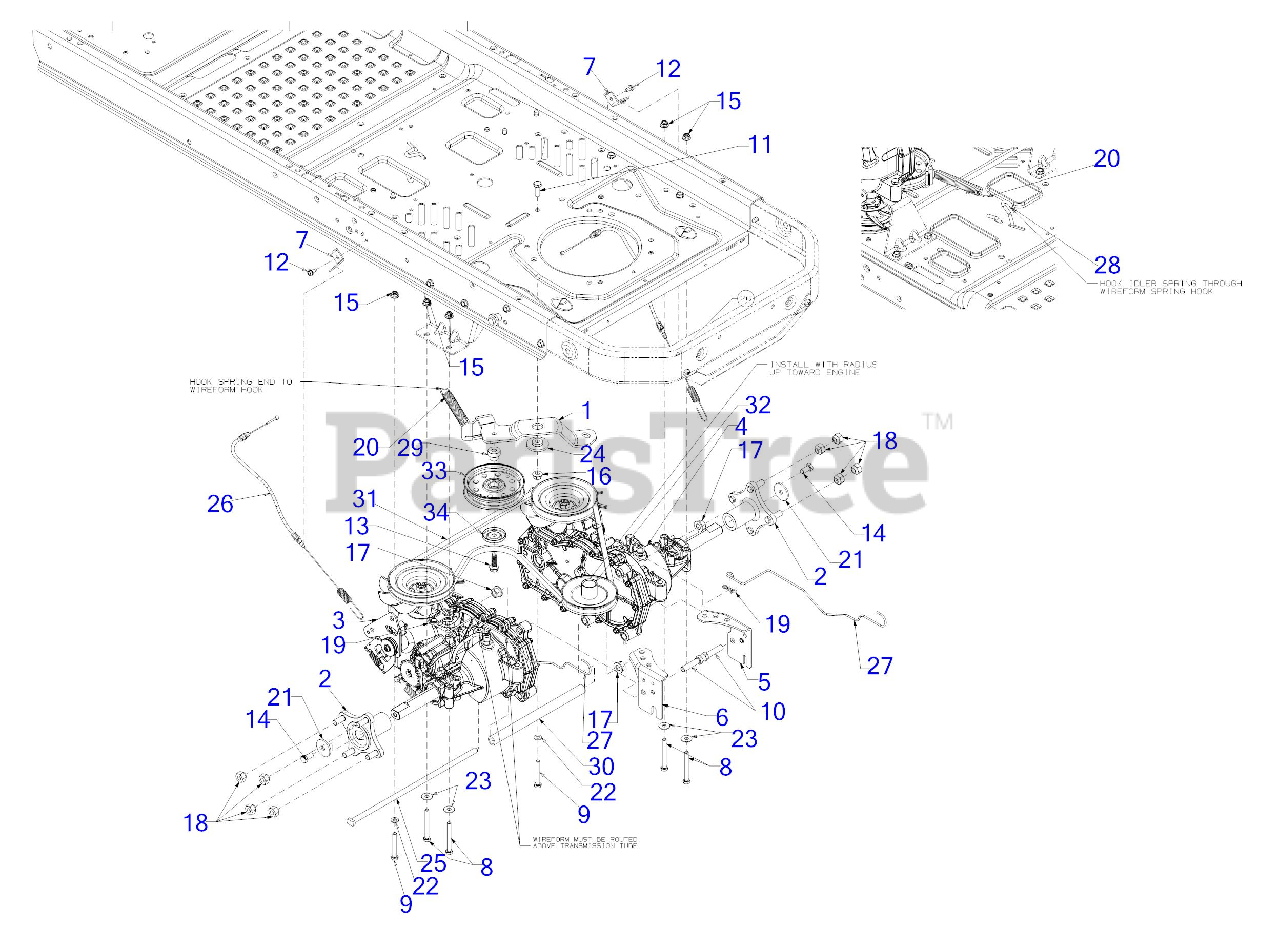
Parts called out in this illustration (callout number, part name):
1	IDLER BRACKET ASSEMBLY
2	WHEEL HUB ASSEMBLY
3	HYDRO TRANSMISSION ASSEMBLY (LH)
4	HYDRO TRANSMISSION ASSEMBLY (RH)
5	TRANSMISSION MOUNTING BRACKET (RH)
6	TRANSMISSION MOUNTING BRACKET (LH)
8	HEX SCREW 5/16-18 x 2.75
9	HEX SCREW 5/16-18 x 2.25 GR5
10	SCREW 7/16-20 x 1.75 GR 5
11	SCREW 3/8-16 x 1 GR5
12	SCREW 1/4-20 X.500
13	SCREW 3/8-16 X1.250
14	SCREW 3/8-16 x .75 GR 5
15	FLANGE LOCK NUT 5/16-18
17	FLANGE LOCK NUT
18	LUG NUT 7/16-14
19	BOW TIE COTTER PIN 1/4-5/16
20	EXTENSION SPRING .75 DIA x 5.87
21	FLAT WASHER .390x1.500x.134
22	FLAT WASHER
23	FLAT WASHER
24	SHOULDER SPACER
25	SUPPORT TUBE ROD
26	PARK BRAK CABLE
27	HYDRO BYPASS ROD
28	IDLER SPRING HOOK
29	SHOULDER SPACER
30	SUPPORT TUBE
31	TRANSMISSION DRIVE BELT A x 67
32	TRANSMISSION DRIVE PULLEY
33	IDLER PULLEY 4.25 DIA
34	IDLER PULLEY CAP
